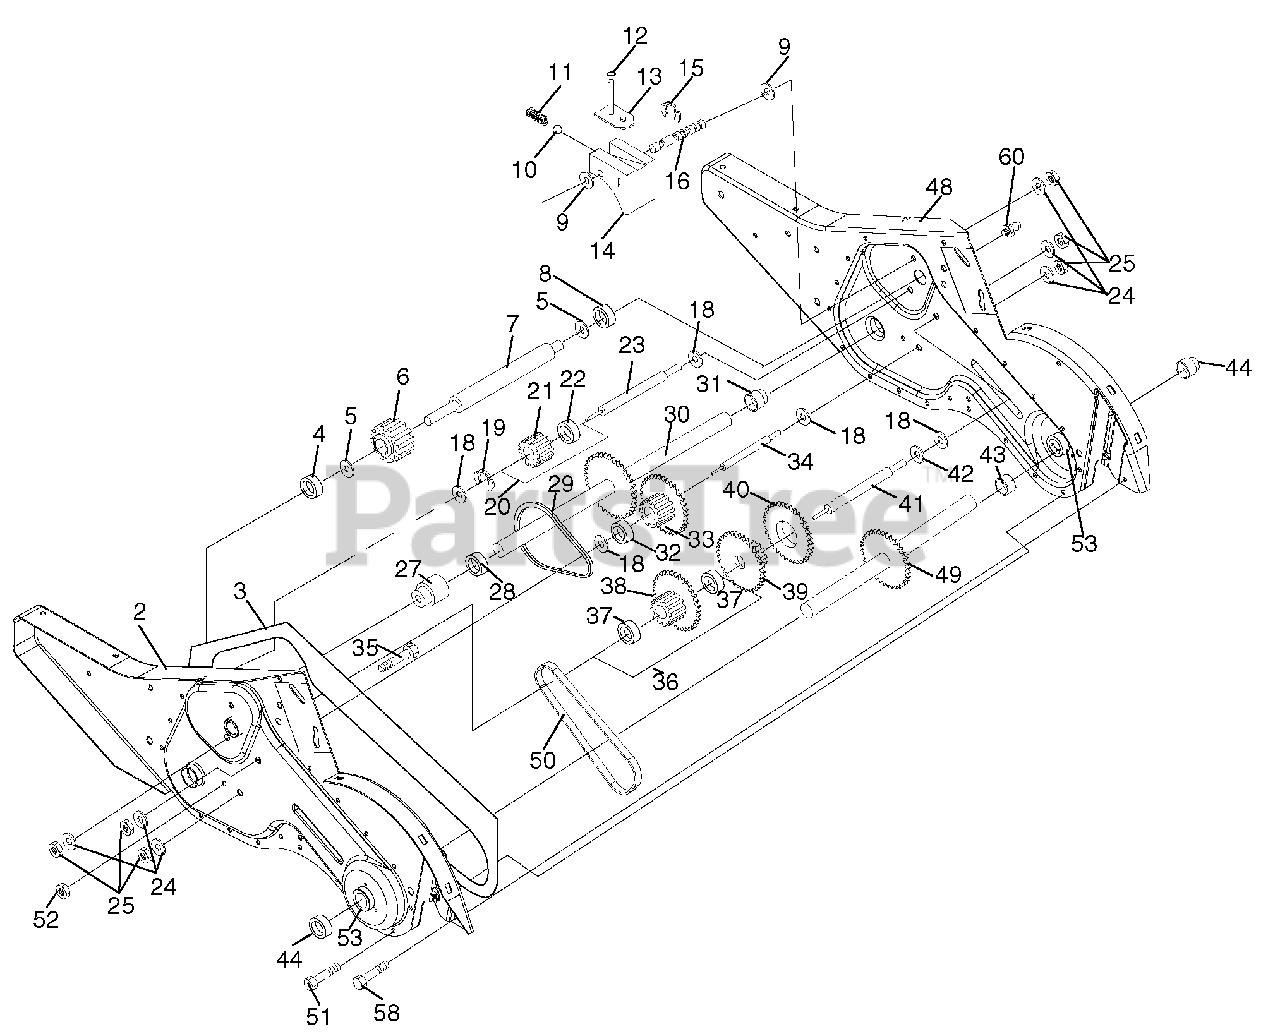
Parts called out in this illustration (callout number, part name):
1	Transmission Assembly
2	Gearcase, L.H. w/Bearing
3	Gasket, Gearcase
4	Bearing, Needle
5	Washer, Thrust 5/8 x 1.10 x 1/32
6	Pinion, Input
7	Shaft, In put
8	Bearing, Needle
9	Washer, Seal
10	Ball, Steel
11	Spring, Shift, Fork
12	O-Ring
13	Asm. Bracket Shift
14	Fork, Shift
15	Ring, Klip
16	Shaft, Shift
18	Washer
19	Ring, Klip
20	Gear, As sem bly, Reverse Idler
21	Gear, Re verse Idler
22	Bearing, Needle
23	Shaft, Re verse Idler
24	Washer, Lock 7/16
25	Nut, Hex 7/16-20
27	Bearing, Shaft, Ground Drive L.H.
28	Spacer 0.765 x 1.125 x 1.23
29	Chain #35-50 Pitch
30	Ground Shaft Assembly
31	Bearing, Shaft, Ground Drive R.H.
32	Spacer 0.70 x 1.00 x 1.150
33	Sprocket and Gear Assembly
34	Shaft, Re duc tion (2nd)
35	Screw, Whiz, Lock 5/16-18 x 3-1/2
36	Sprocket Assembly w/Bearing
37	Bearing, Needle
38	Sprocket, Tine
39	Gear, Clus ter, Red 1st & 2nd
40	Gear, Re verse
41	Shaft, Re duc tion (1st)
42	Washer, Thrust
43	Spacer 1.01 x 1.75 x 0.760
44	Seal Asm, Oil
48	Gearcase, R.H. w/Bearing
49	Shaft, Tine
50	Chain, Roller #50-50 Pitch
51	Screw 1/4-20 x 1/2
52	Nut, Hex 5/16-18
53	Kit, Bearing
58	Bolt Shoulder
60	Fitting Grease
60	Grease, Plastilube #1
